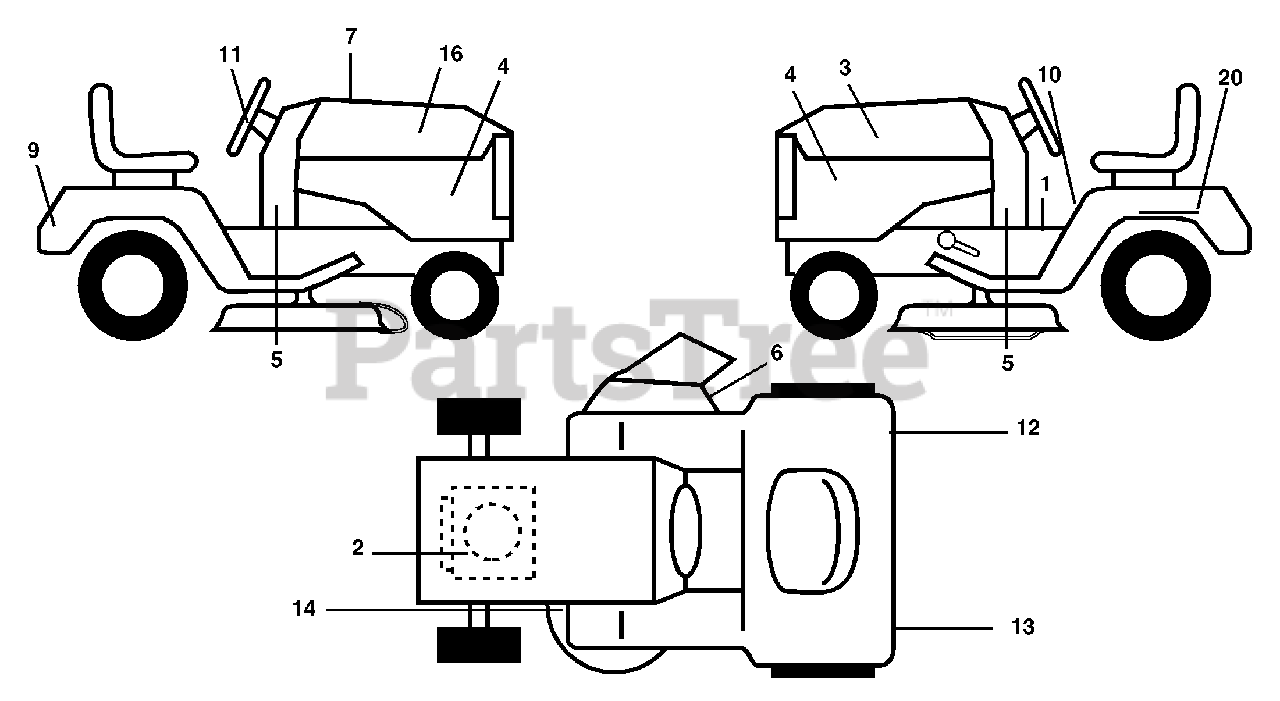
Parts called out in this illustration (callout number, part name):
2	Decal Engine
3	Decal Hood LH
4	Decal Side Panel Logo
5	Decal Dash
6	Decal Warning, Keep Hand Away
7	Decal Replacement Parts
9	Decal Fender Logo
10	Decal Fender Danger E/F
11	Decal Ins Strg Whl
12	Decal Fend Refl ector Rh
13	Decal Fend Refl ector Lh
14	Decal V-Belt Schematic
16	Decal Hood Rh
20	Decal Bat Dan/Psn
